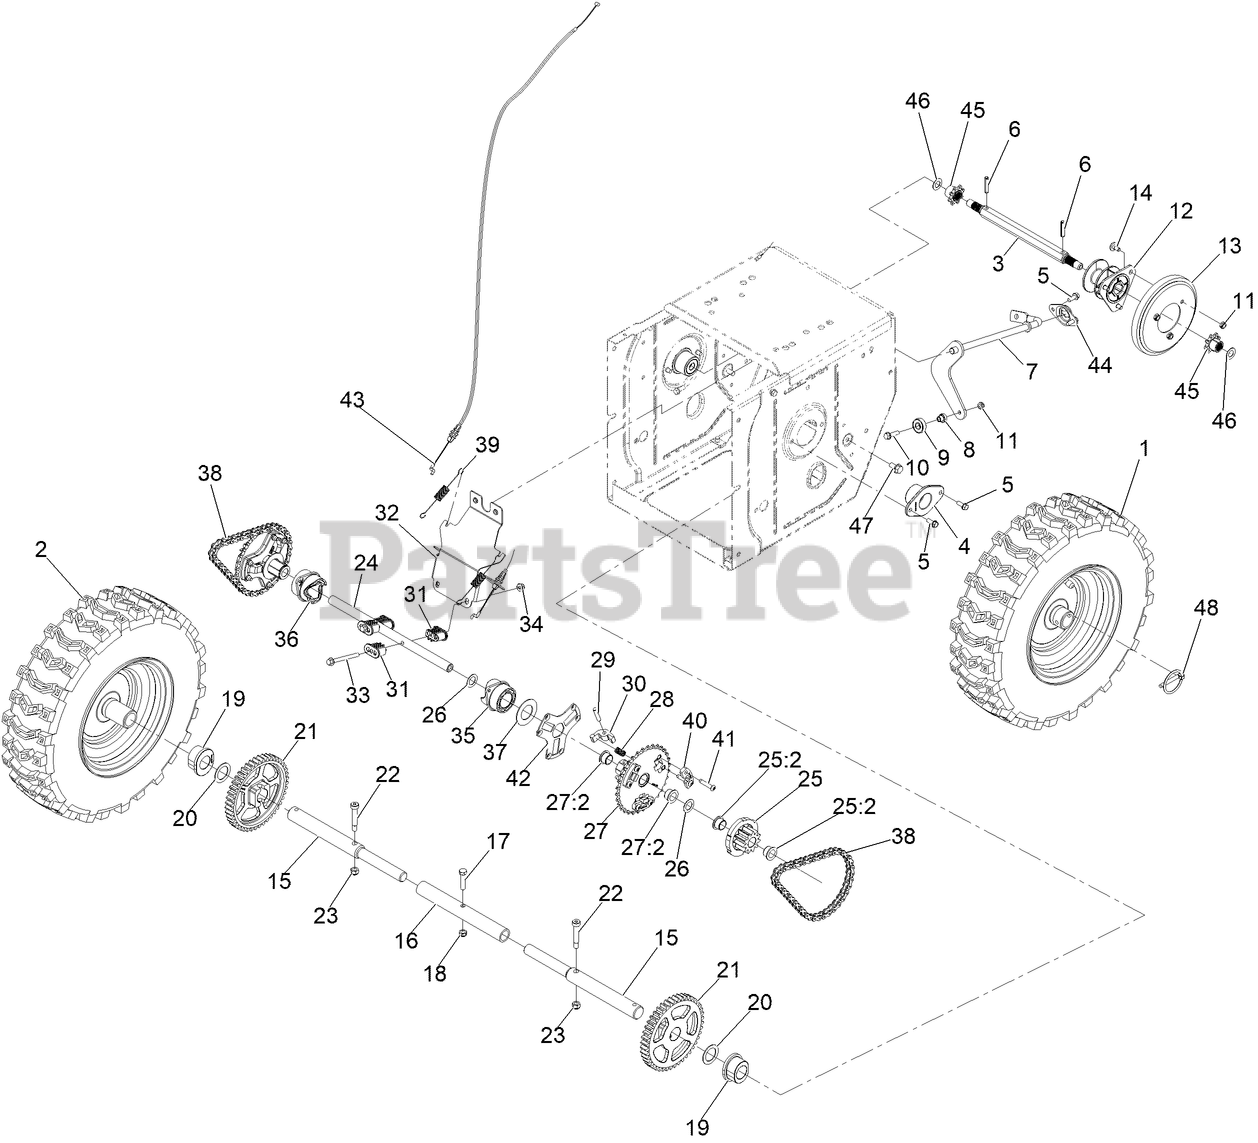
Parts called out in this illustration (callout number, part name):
1	LH WHEEL AND TIRE ASM
2	RH WHEEL AND TIRE ASM
3	SHAFT-HEX
4	RETAINER-BEARING
5	SCREW-HWH
6	PIN-ROLL, SLOTTED
7	Rod-Shift
8	SPACER-PLATE, SHIFT
9	BEARING-BALL
10	SCREW-HWHTF
11	NUT-HEX
12	TRUNNION
13	WHEEL-FRICTION
14	SCREW-SHOULDER
16	TUBE-AXLE
17	SCREW-HH
18	NUT-HEX
19	BUSHING-AXLE
20	WASHER-THRUST
21	GEAR-AXLE
22	BOLT-SHOULDER, HSH
23	NUT-HEX
24	SHAFT-INTERMEDIATE
25	11T GEAR ASM
25:2	BUSHING-FLANGE
26	WASHER-FLAT
27	32T SPROCKET ASM
27:2	BUSHING-FLANGE
28	SPRING-COMPRESSION
29	PIN-DOWEL
30	PAWL-CLUTCH
31	GUIDE-COLLAR
32	BRACE-SHIFT, COLLAR
33	SCREW-HHF
34	SCREW-SHOULDER
35	COLLAR-SHIFT, LH
36	COLLAR-SHIFT, RH
37	WASHER-THRUST
38	CHAIN-ROLLER
39	SPRING-EXTENSION
40	SUPPORT-PAWL
41	SCREW-BHCS
42	RETAINER-PAWL, PIN
43	Cable-Clutch
44	RETAINER-ROD, SHIFT
45	GEAR-PINION, 8 TOOTH
46	WASHER-PLAIN
47	SCREW-HWHTF
48	PIN-KLIK
